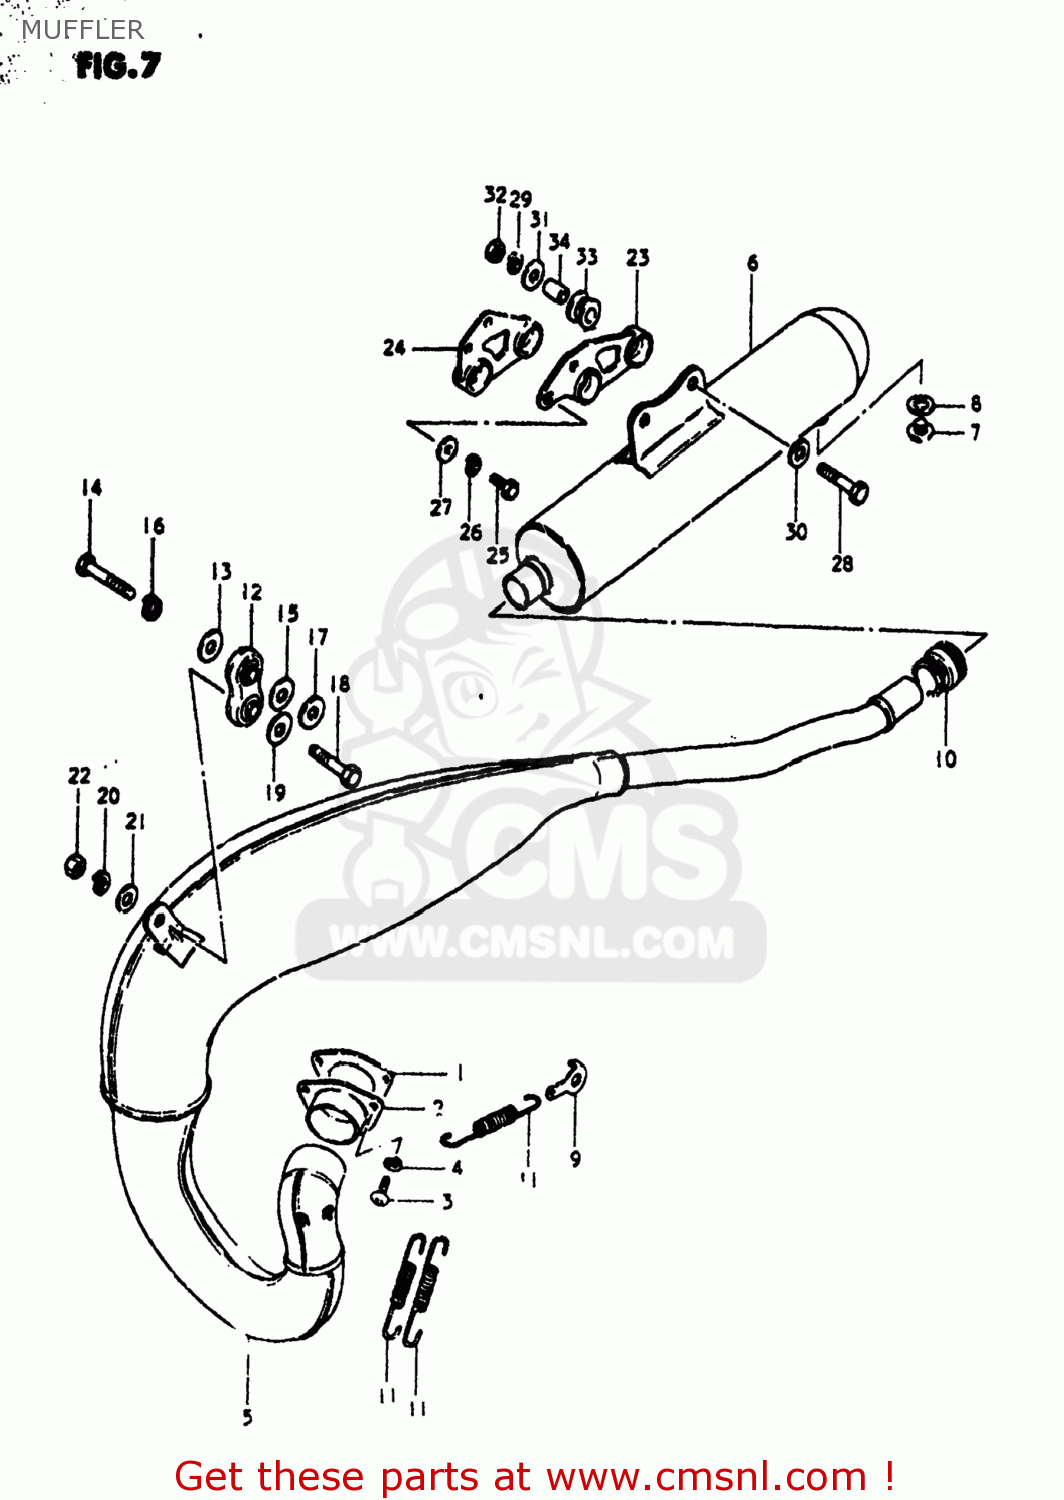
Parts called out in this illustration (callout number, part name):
1	GASKET,EXHAUST PIPE (MCA)
2	FLANGE,EXHAUST PIPE
3	SCREW
4	LOCK WASHER
5	BODY,MUFFLER
6	MUFFLER ASSEMBLY,SECOND
7	PLUG(12X9)
8	GASKET(12X16X2) (NAS)
9	HOOK,MUFFLER FIT SPRING
10	CONNECTOR,MUFFLER
11	SPRING
12	DAMPER,MUFFLER
13	WASHER
14	BOLT 8X45
15	WASHER
16	LOCK WASHER
17	SPACER(8.4X12X12)
18	BOLT
19	WASHER
20	LOCK WASHER
21	WASHER
22	NUT
23	DAMPER,MUFFLER SUPPORT
24	DAMPER,MUFFLER SUPPORT
25	BOLT
26	LOCK WASHER
27	WASHER
28	BOLT
29	LOCK WASHER
30	WASHER
31	WASHER (8.5X29X1.6)
32	NUT
33	CUSHION
34	SPACER (8.2X12X17)
